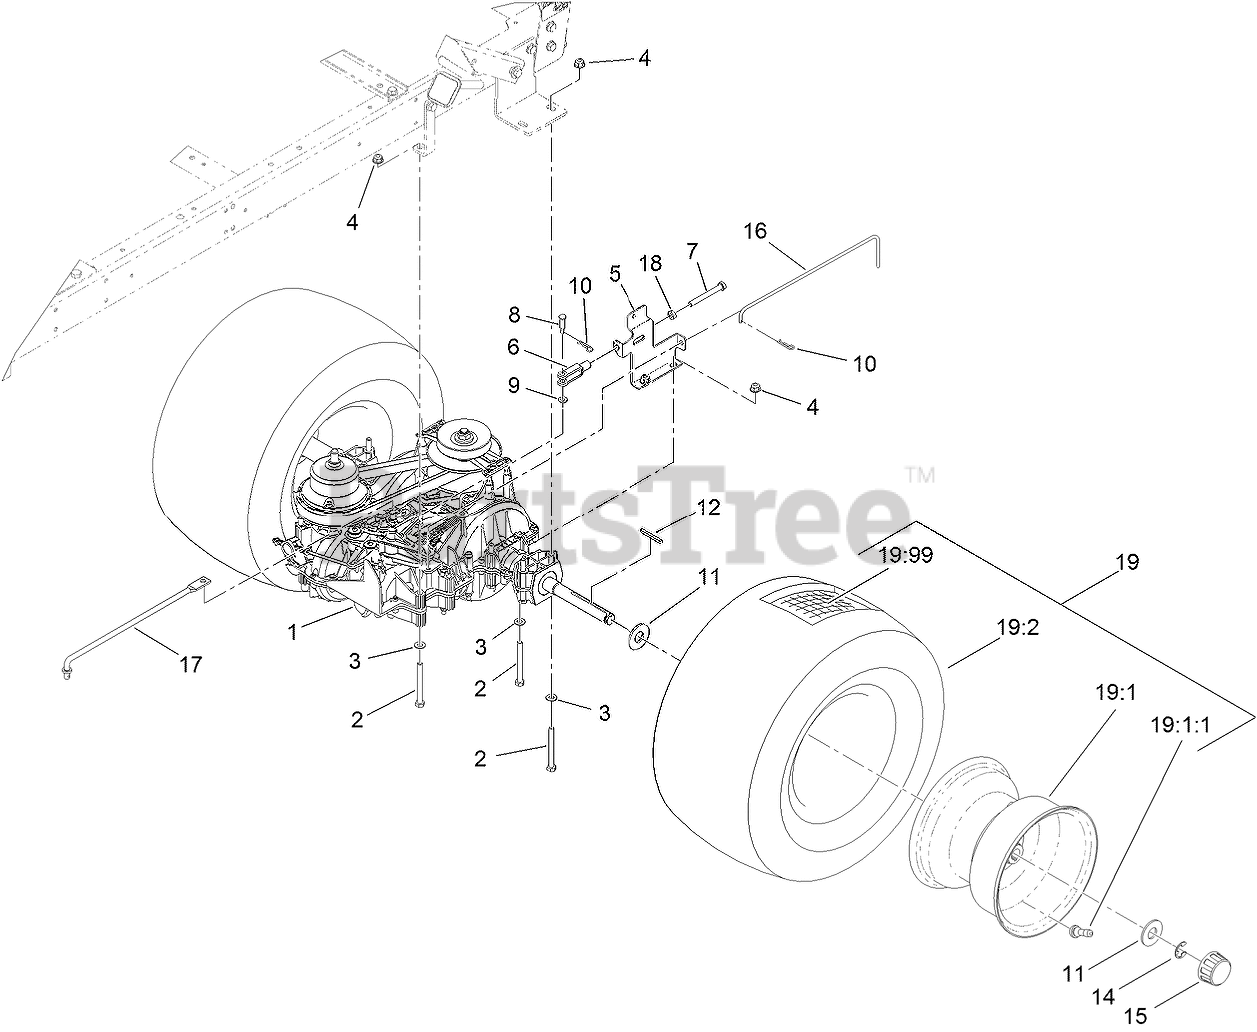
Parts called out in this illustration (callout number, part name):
1	TRANSMISSION ASM
2	SCREW-HH
3	WASHER-PLAIN
4	NUT-HF, NI
5	BRACKET-NEUTRAL
6	YOKE-ADJUSTABLE
7	SCREW-HH
9	WASHER-FLAT
10	PIN-COTTER
11	WASHER-PLAIN
12	KEY-SQUARE
14	E-RING
15	CAP-HUB
16	ROD-BYPASS
17	ROD-MOTION CONTROL, REAR
18	NUT-JAM
19	WHEEL AND TIRE ASM
19:1:1	STEM-VALVE
19:2	TIRE-4 PLY
19:99	Tube
